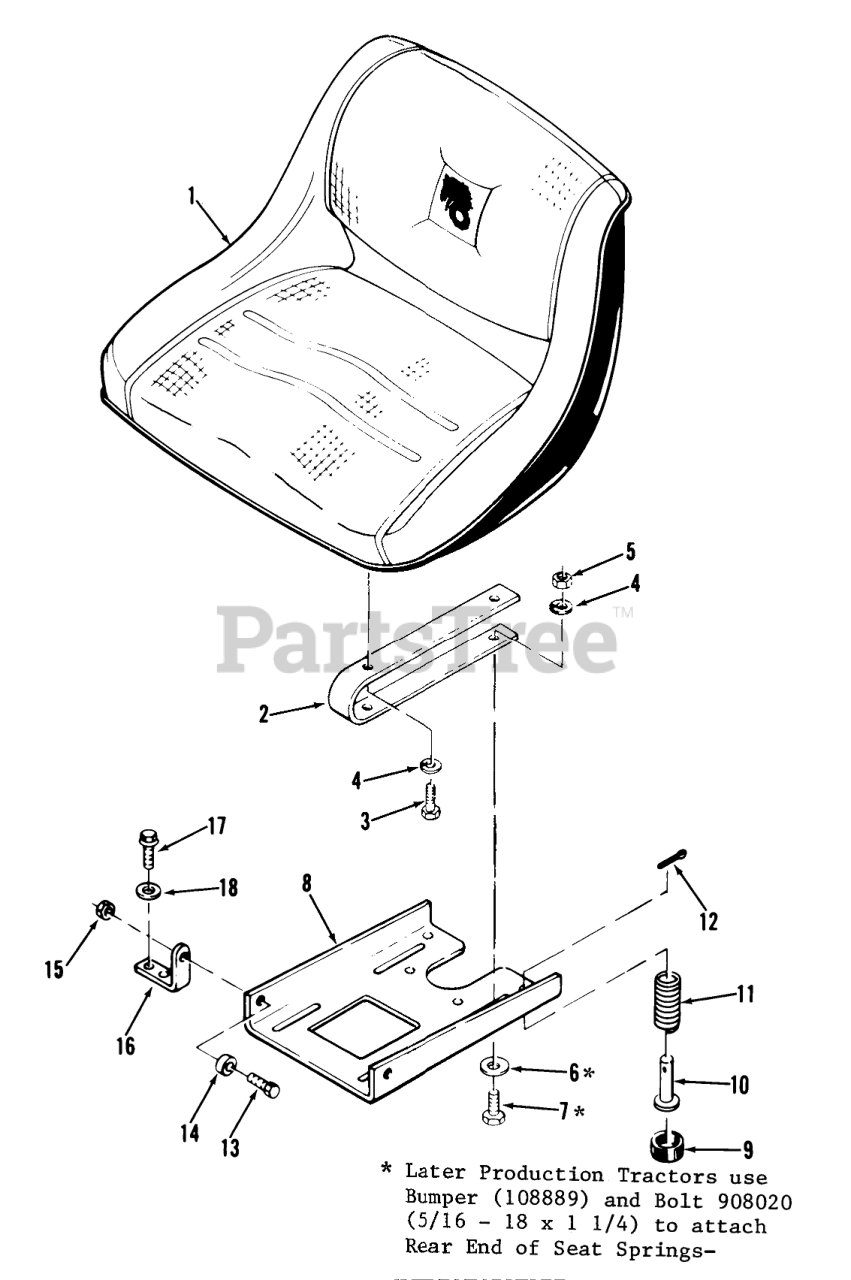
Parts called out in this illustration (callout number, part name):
1	Seat
2	Spring
3	Bolt
4	Lockwasher
5	Nut
6	WASHER 5/16 SAE
7	HHCS
8	Pivot Plate
11	SPRING
12	Cotter Pin
13	HHCS
14	BUSHING
15	Nut
16	BRACKET-PIVOT
17	SEAT BOLT FOR C195
18	WASHER 5/16 SAE
